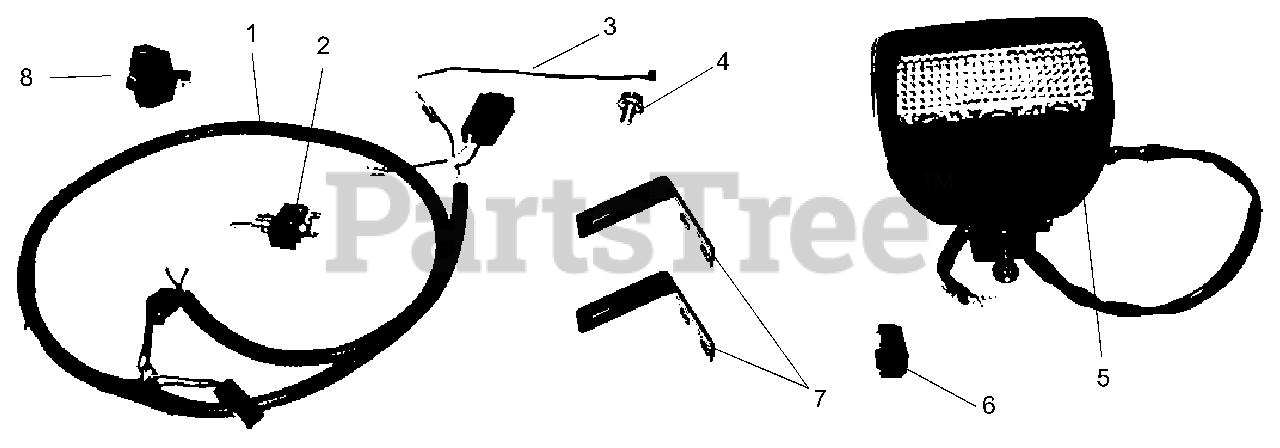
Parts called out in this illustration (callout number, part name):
1	Headlight Harness
2	Headlight Switch
3	Cable Tie
4	3/8" x 1/2" Tapping Screw
5	Headlight
6	Connector Shell
7	Headlight Mounting Bracket
8	Light Switch
